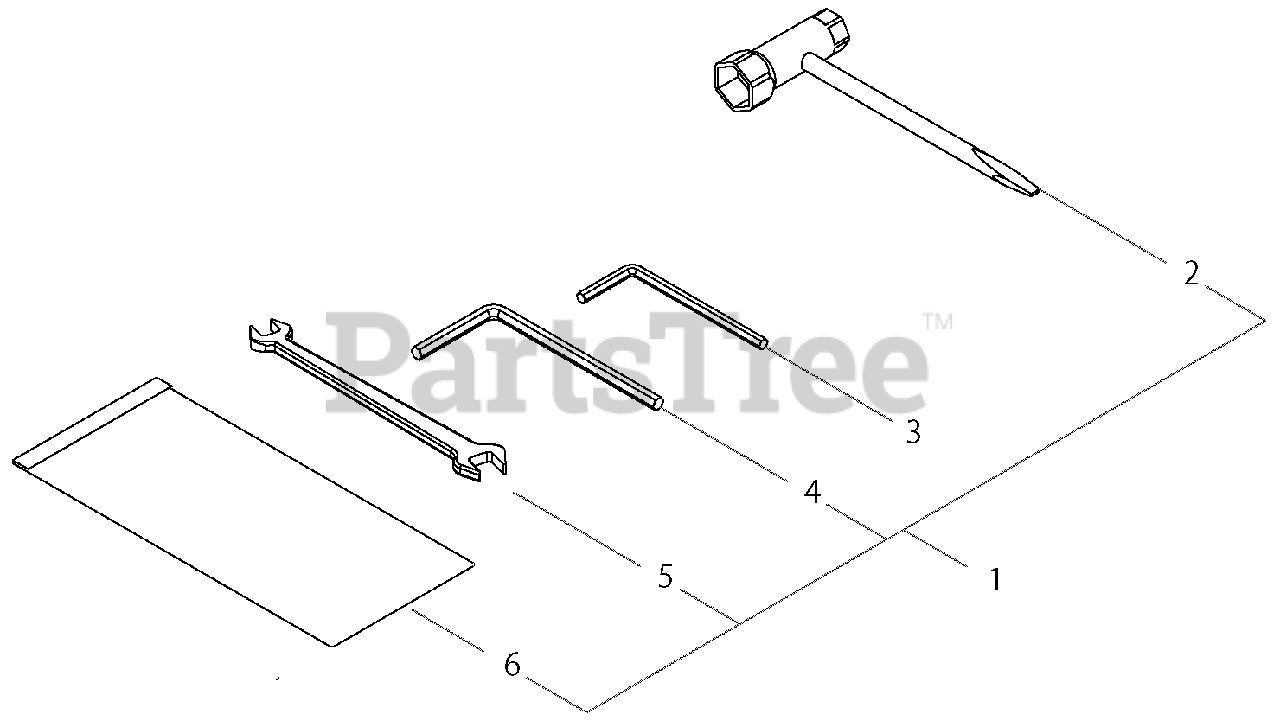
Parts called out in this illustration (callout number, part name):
1	TOOL KIT
2	T-WRENCH - 17X19mm
3	HEX KEY - 4mm
4	HEX KEY - 6mm
5	SPANNER - 8X10mm
6	BAG, TOOL
